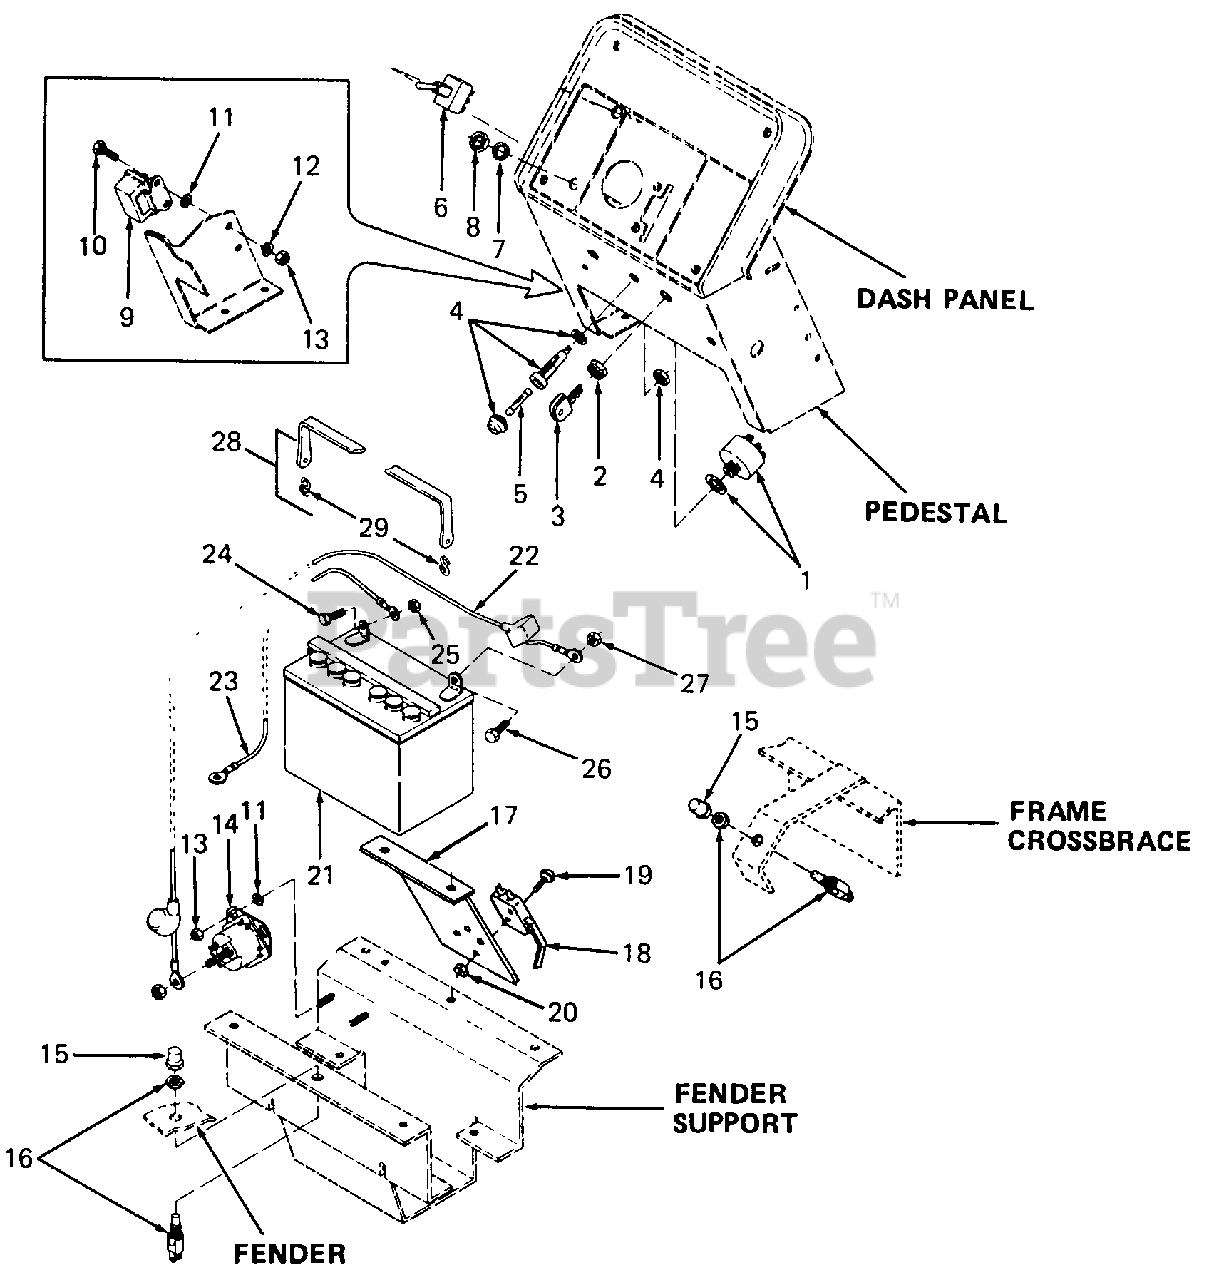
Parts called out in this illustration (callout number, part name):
1	Switch, Ignition Key
2	Nut, Switch
3	Key, Ignition (Set of 2)
4	Fuse Holder
5	Fuse, 20 Amp
6	Switch, PTO
7	Washer, Flat, .531 X .680 X .054 Thk
8	Nut, Hex, 1/2-27 X .100 Thk
9	Relay
10	Screw, Hex Cap, 1/4-20 X .62 Lg GR5
11	Washer, Ext Lock, 1/4
12	Washer, Lock, 1/4
13	Nut, Hex, 1/4-20 GR5
14	Solenoid
15	Boot, Switch
16	Switch w/Nut
17	Bracket, Micro Switch
18	Switch, Reverse
19	Screw, Hex Mach, #4-40 X .75 Lg
20	Nut, Hex Insert Lock, #4-40
21	Battery
22	Cable, Positive Battery
23	Cable, Negative Battery
24	Bolt, Carriage, 1/4-20 X .75 Lg
25	Nut, Hex, 1/4-20 GR5
26	Bolt, Carriage, 5/16-18 X .75 Lg
27	Nut, Hex, 5/16-18 GR5
28	Strap Assy, Battery
29	Hook, Battery Strap
